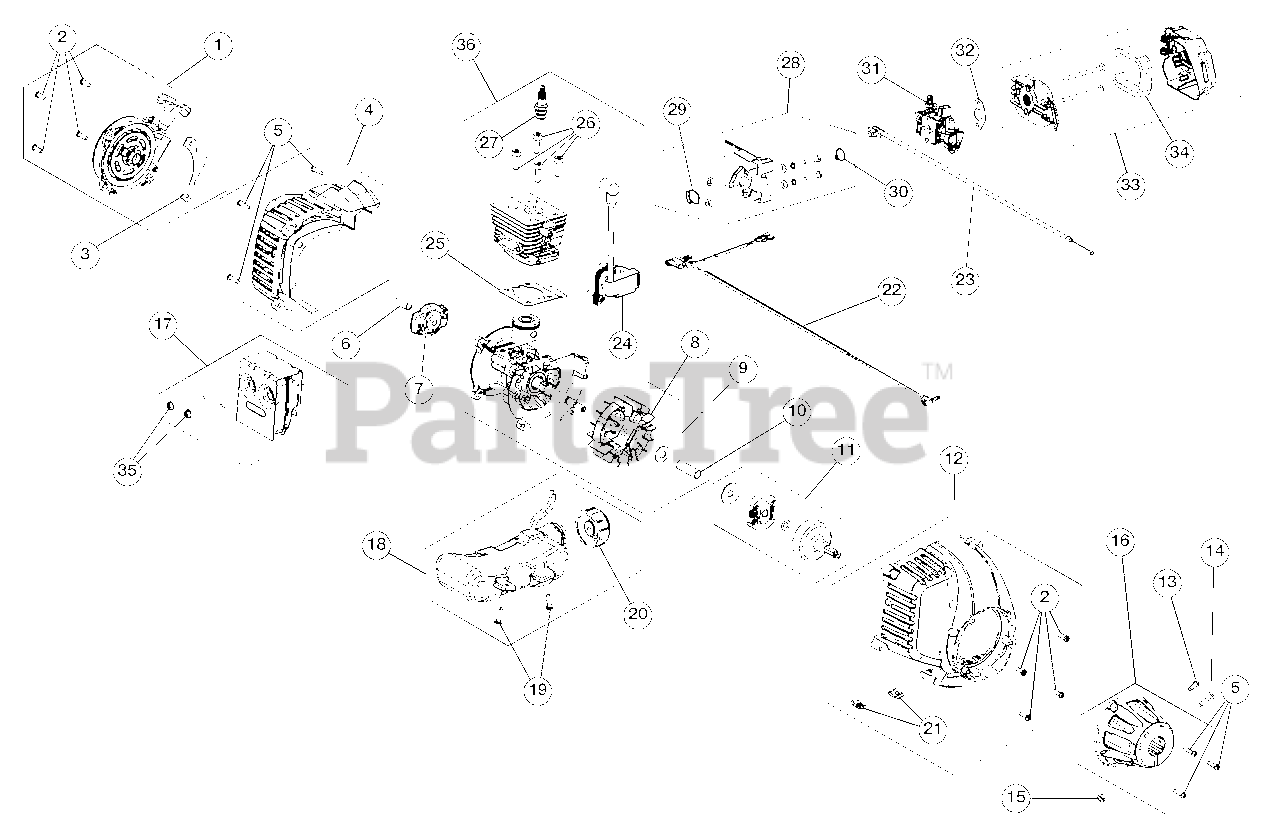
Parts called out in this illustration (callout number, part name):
1	Rear Cover Assembly (Incl. 2 & 3)
2	Starter Screw
3	Starter Assembly Guard (Incl. 2)
4	Rear Engine Cover Assembly (Incl. 5)
5	Cover Screw
6	Adapter
7	Pawl Assembly
8	Flywheel Assembly
9	Washer
10	Spacer
11	Clutch Assembly
12	Front Engine Cover Assembly (Incl. 2 & 21)
13	Anti-Rotation Screw
14	Clamp Screw
15	Clamp Nut
16	Clutch Cover Assembly (Incl. 5)
17	Muffler Assembly (Incl. 35)
18	Fuel Tank Assembly (Incl. 19 & 20)
19	Tank Screw
20	Fuel Cap
21	U-Shaped Nut
22	Lead Wires
23	Throttle Cable
24	Module Assembly
25	Cylinder Gasket
26	Cylinder Bolt
27	Spark Plug
28	Insulator Assembly (Incl. 29 & 30)
29	Insulator O-Ring
30	Carburetor O-Ring
31	Carburetor
32	Carburetor Gasket
33	Air Cleaner Assembly (Incl. 34)
34	Air Cleaner Filter
35	Muffler Screws
36	Short Block Assembly
